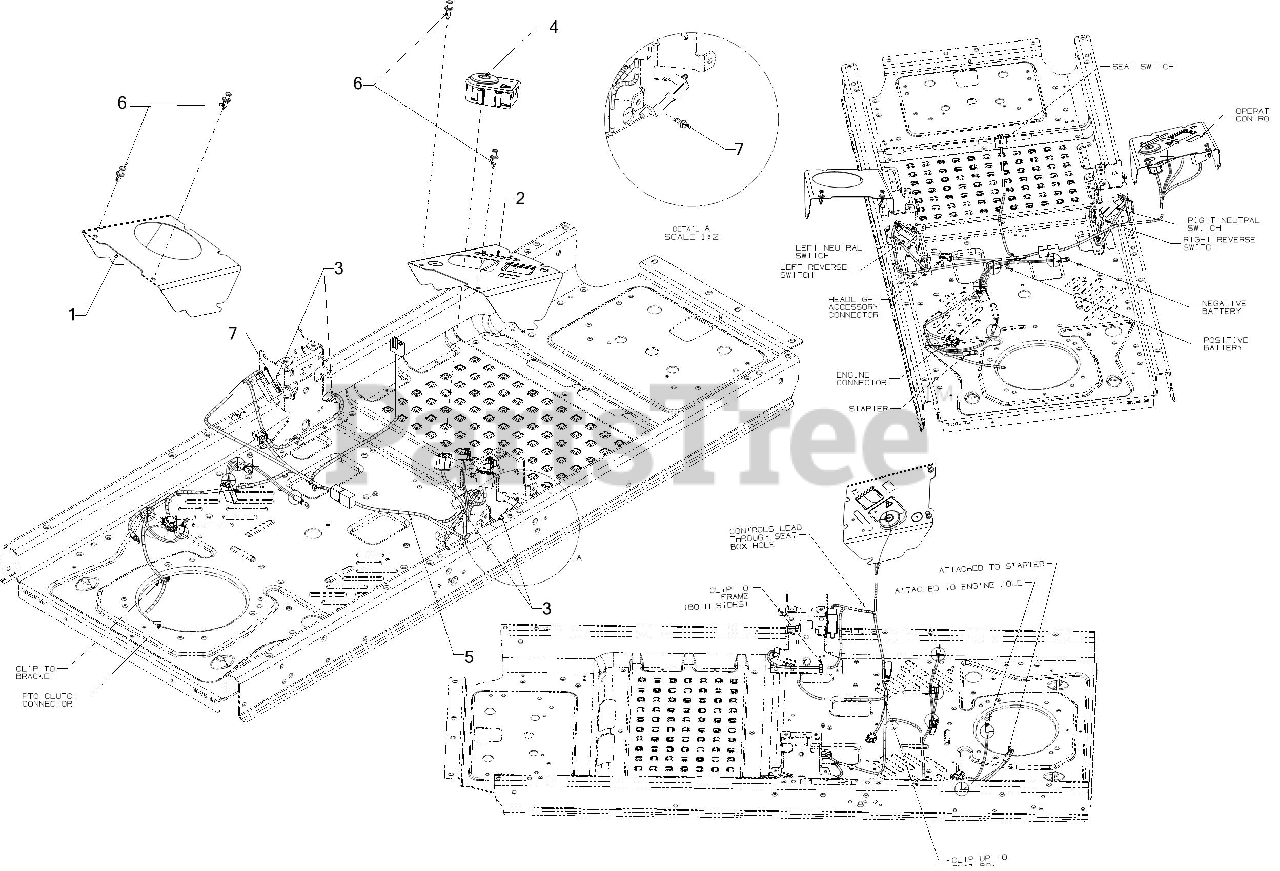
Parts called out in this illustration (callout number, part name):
1	CONSOLE COVER (LH)
2	CONSOLE COVER (RH)
3	INTERLOCK SWITCH (NO/NC)
4	KEY SWITCH MODULE 8 PIN
5	MAIN HARNESS
6	PLASTIC RIVET
7	SHOULDER SCREW
